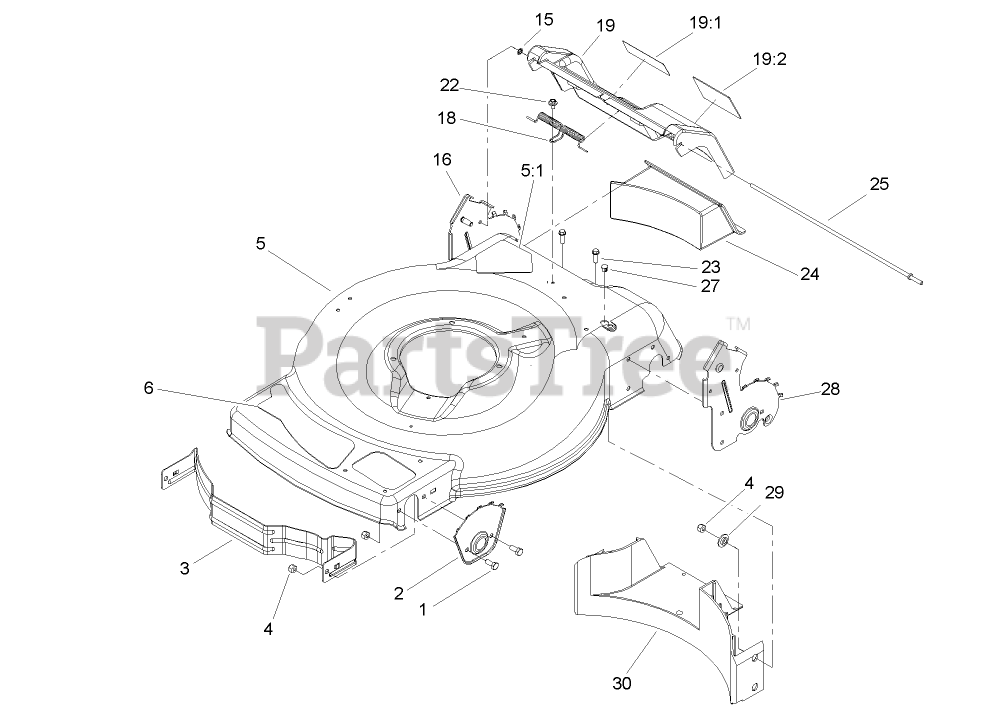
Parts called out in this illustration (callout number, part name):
1	SCREW-HH
2	Plate-HOC, Front
3	Baffle-Front
4	NUT-LOCK, NI
5	HOUSING ASM
5:1	DECAL-DANGER
6	Decal-Deck
15	NUT-PUSH
16	RH REAR HOC PLATE ASM
18	Spring-Door, Rear
19	REAR DOOR ASM
19:1	DECAL-WARNING
19:2	DECAL-WARNING
22	SCREW AND WASHER ASM
23	SCREW-HWH
24	Plug-Discharge, Rear
25	Rod-Pivot, Rear Door
27	Plug-Dome
28	LH REAR HOC PLATE ASM
29	Washer-Stepped
30	Baffle-Rear
